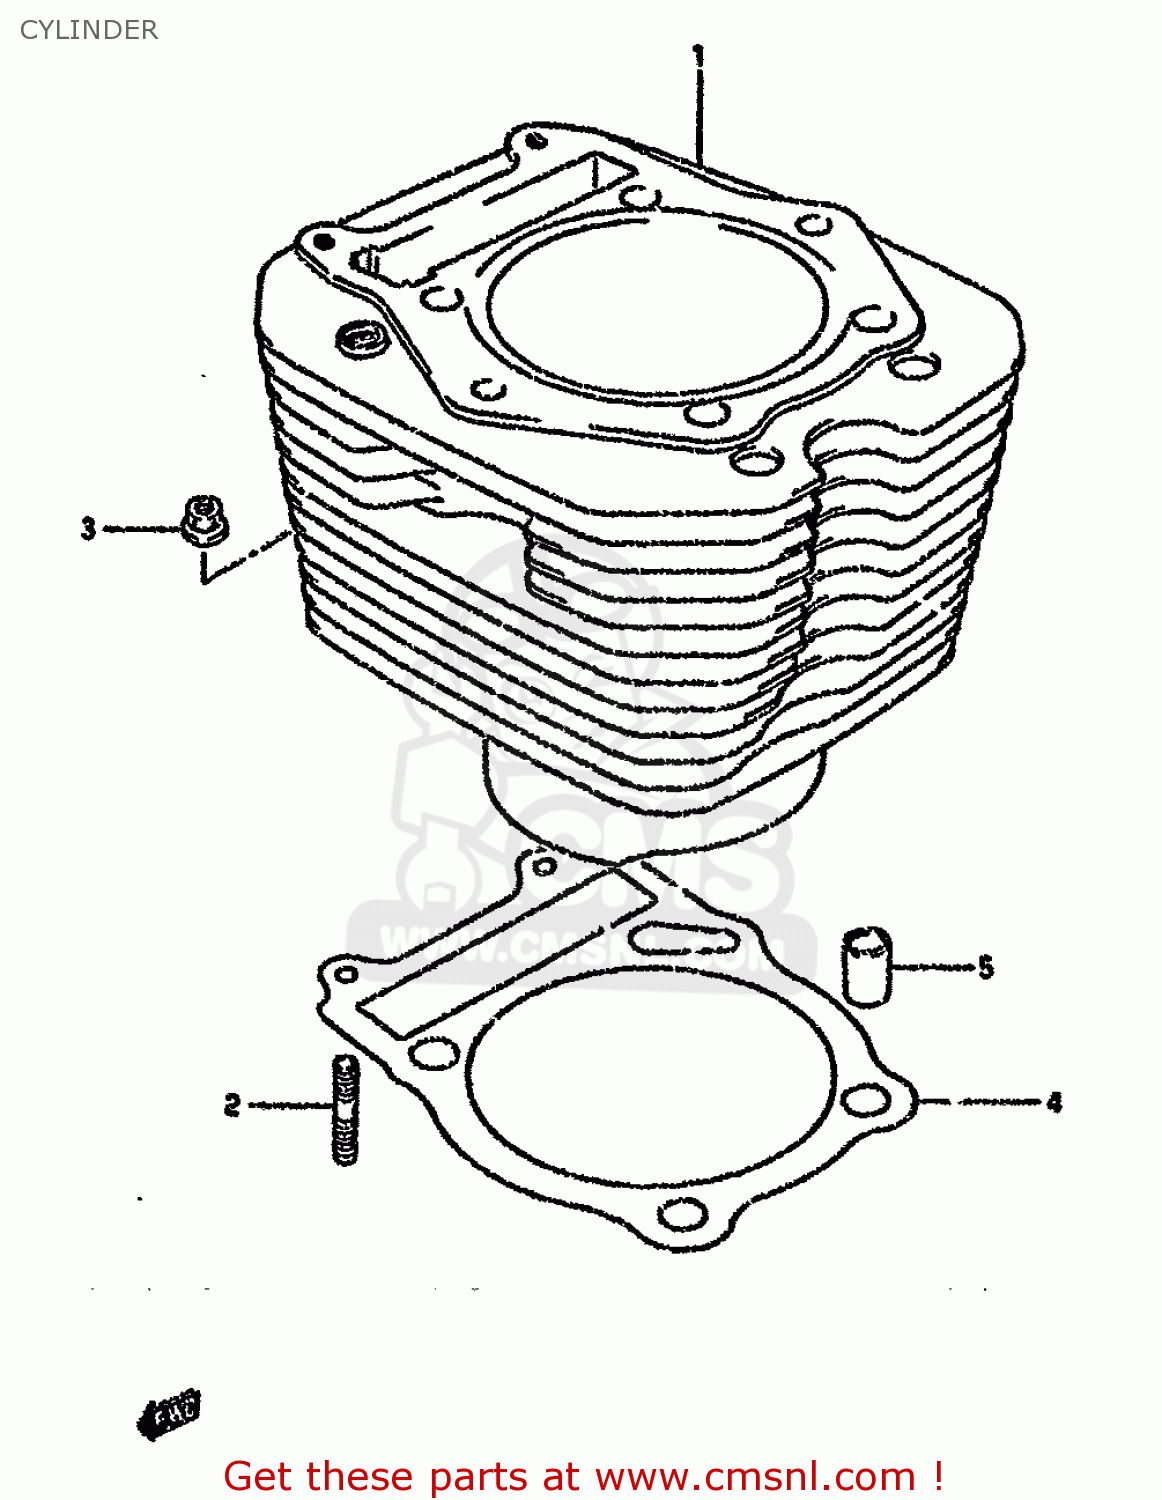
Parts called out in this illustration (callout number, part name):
1	CYLINDER
2	STUD 6X20
3	NUT
4	GASKET,CYLINDER (NAS)
5	PIN
